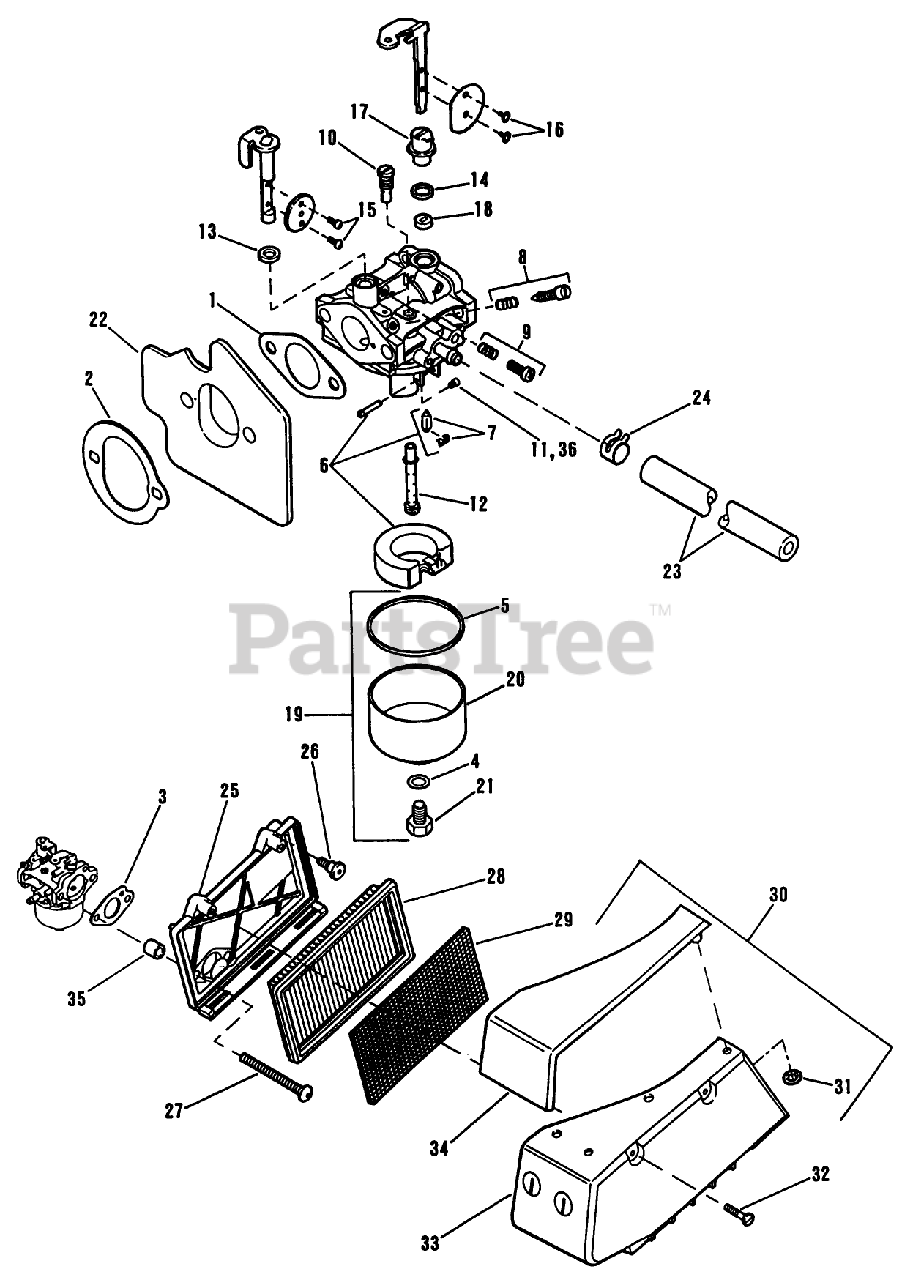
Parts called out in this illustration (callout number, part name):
1	GASKET SM
2	GASKET SM
3	GASKET-FIL SM
4	GASKET-BOWL RET S
5	GASKET-FUELBOWL S
7	NEEDLE & CLIP S
10	PILOT JET
11	CARB JET
14	SEAL CHOKE SHAFT
16	SCREW CHOKE VALVE
21	SCREW,BOWL RET S
22	SPACER & NOZZ SM
23	GAS LINE SM
24	HOSE CLAMP SM
28	ELEMENT-AIR SM
31	NUT-PUSH
36	MAIN JET
